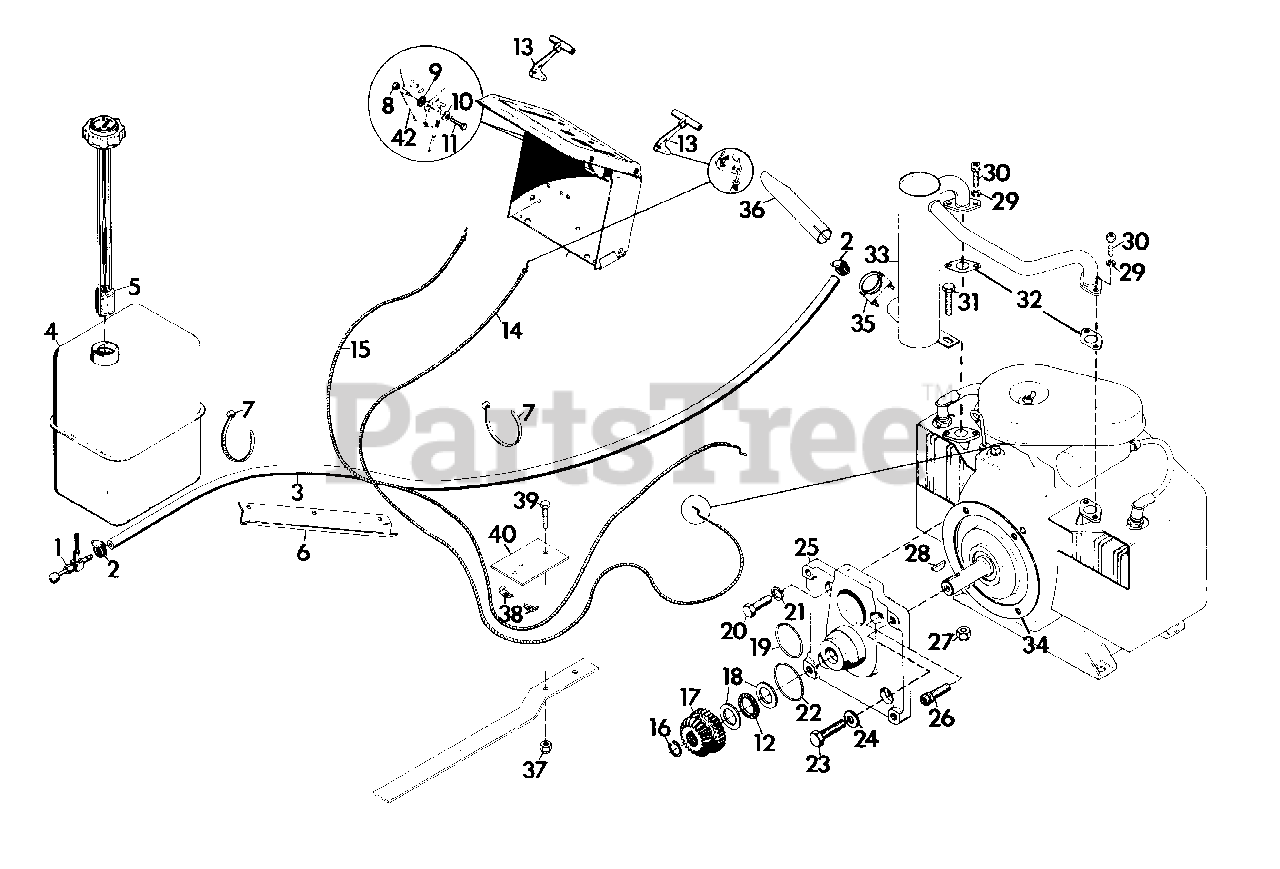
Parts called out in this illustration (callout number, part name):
1	VALVE, FUEL 90 DEG. REVERSE FLOW
2	CLAMP, HOSE
3	LINE, FUEL
4	TANK, FUEL
5	GAUGE, GAS
6	SHIELD, HEAT
7	TIE, CABLE
8	NUT, LOCK 1/4-28
9	WASHER, FRICTION
10	WASHER, SPRING
11	BOLT, HEX 1/4-28X.75
12	BEARING, THRUST 1.127X1.740X.078
13	ASSEMBLY, KNOB AND LEVER
14	ASSEMBLY, CHOKE CONDUIT
15	ASSEMBLY, THROTTLE CONDUIT
16	RING, RETAINING 1.125 SHAFT
17	GEAR, SPUR AND BEVEL, INPUT
18	RACE, BEARING THRUST 1.127X1.74X.06
19	O-RING, 2.500X2.750X.125
20	BOLT, HEX 7/16-14X1.125
21	WASHER, LOCK 7/16 SP HEAVY
22	O-RING, 3.000X3.188X.094
23	BOLT, HEX 1/2-13X1.25
24	WASHER, LOCK 1/2 REG.
25	ADAPTOR, ENGINE
26	SCREW, CAP 7/16-14X1.00 SOCKET HEAD
27	NUT, LOCK 3/8-16
28	KEY, SQUARE .250X1.250
29	WASHER, LOCK 5/16 REG.
30	SCREW, CAP 5/16-18X.75 SOCKET HD
31	BOLT, HEX 3/8-16X1.25
32	GASKET, EXHAUST
33	MUFFLER
34	GASKET, ENGINE
35	CLAMP, MUFFLER
36	EXTENSION, PIPE
37	NUT, LOCK 1/4-20
38	CLIP, SPEED
39	BOLT, HEX 1/4-20X1.00
40	BRACKET, BOWDEN WIRE
41	ENGINE, 17-HP KOHLER TWIN
41	ENGINE, 19-HP KOHLER TWIN
42	BRACKET, MOUNTING
NS	NUT, LOCK 10-32
NS	SCREW, MACHINE 10-32X.50 PHD
